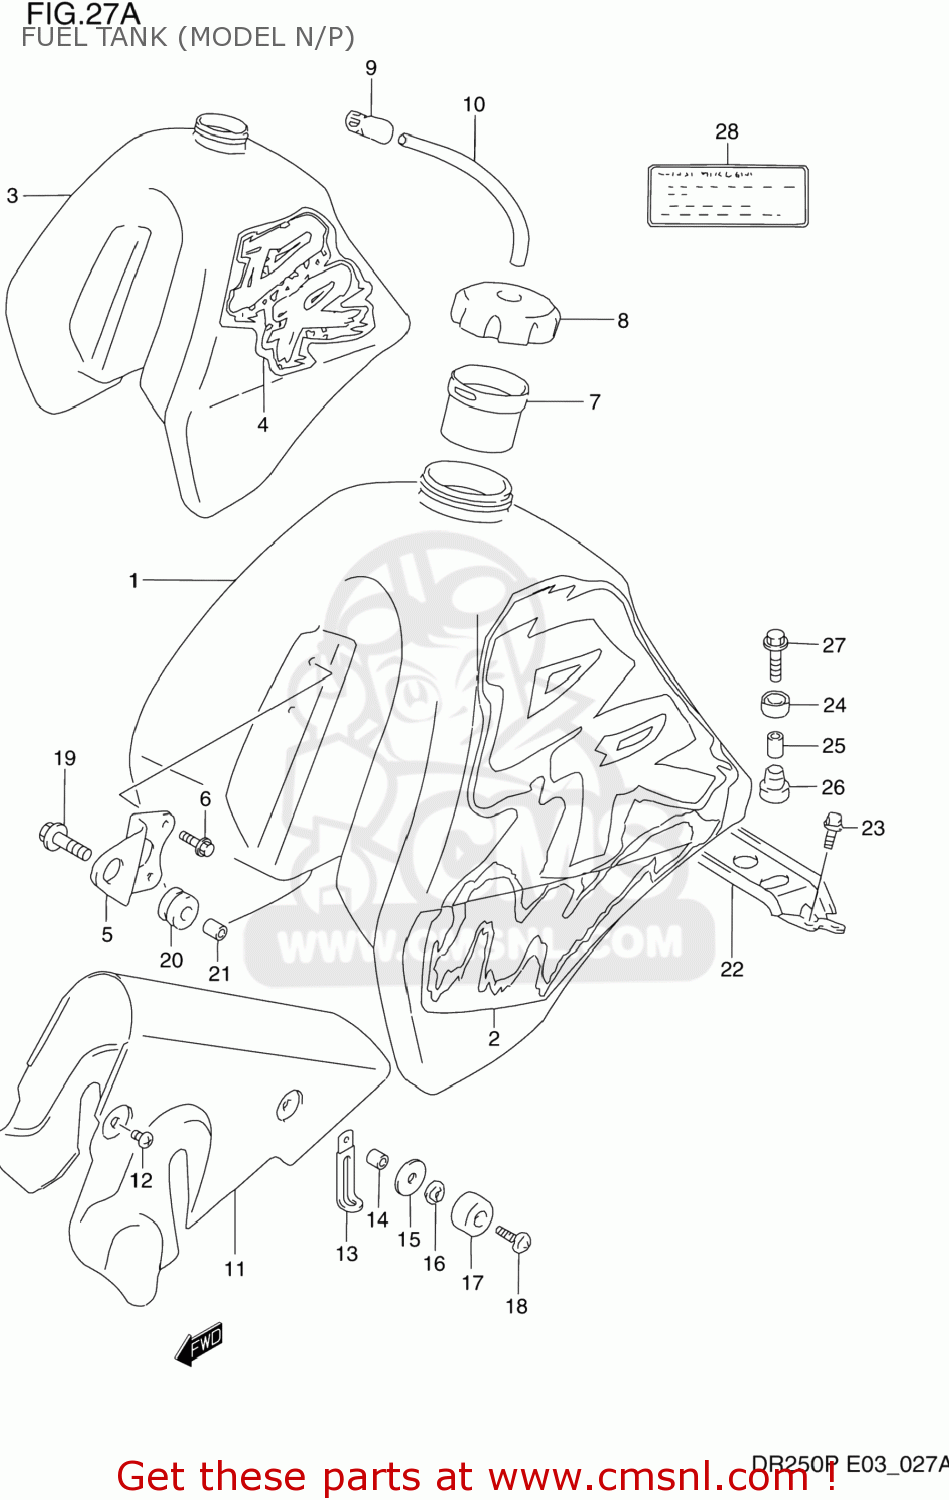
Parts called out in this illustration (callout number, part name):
1	TANK ASSEMBLY,FUEL
2	TAPE SET,FUEL TANK
3	TANK ASSEMBLY,FUEL
4	TAPE SET,FUEL TANK
5	BRACKET,FUEL TANK,FRONT
6	BOLT
7	TUBE,FILLER INLET
8	CAP ASSY,FUEL TANK
9	CLAMP,FUEL TANK BREATHER HOSE
10	HOSE
11	HEAT SHIELD,FUEL TANK
12	SCREW
13	CLAMP
14	SPACER(6.1X14X7.2)
15	WASHER (6.5X26X2.3)
16	WASHER
17	CUSHION
18	SCREW
19	BOLT(8X25)
20	CUSHION
21	SPACER (8.8X12X12.5)
22	BRACKET,FUEL TANK RR
23	BOLT
24	CUSHION
25	SPACER
26	CUSHION
27	BOLT
28	LABEL,STARTING CAUTION
